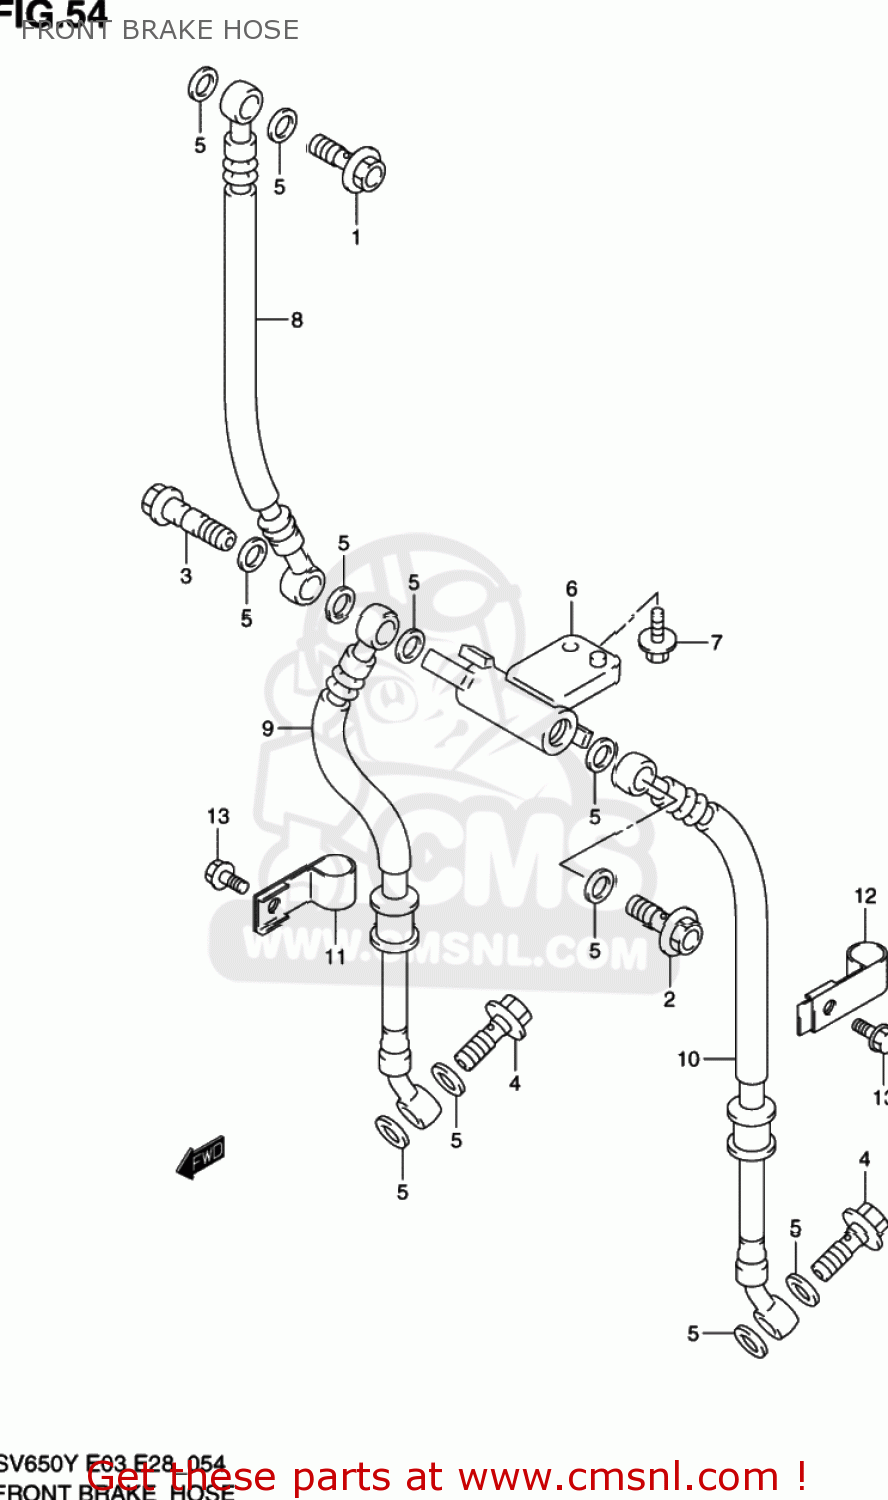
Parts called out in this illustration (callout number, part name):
1	BOLT UNION
2	BOLT UNION
3	BOLT UNION
4	BOLT UNION
5	WASHER(10X15X1.5)
6	JOINT,BRAKE HOSE
7	BOLT
8	HOSE COMP,FRONT BRAKE
9	HOSE COMP,FRONT BRAKE
10	HOSE COMP,FRONT BRAKE
11	CLAMP,FR BRAKE HOSE NO.2
12	CLAMP,FR BRAKE HOSE NO.2,L
13	BOLT
